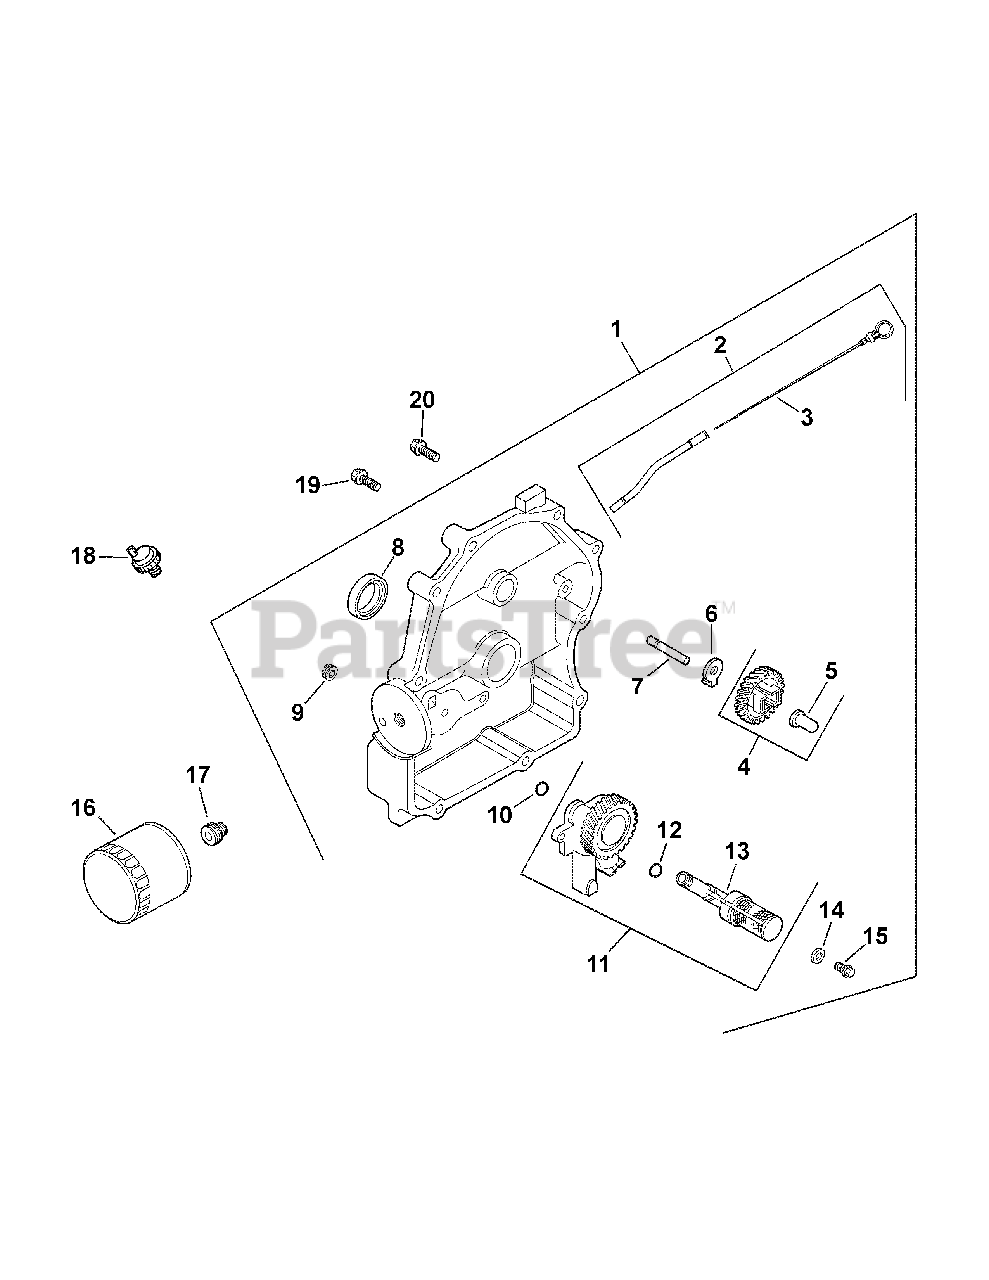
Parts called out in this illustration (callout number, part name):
1	Plate, closure ass’y
2	Kit, tube w/dipstick
4	Kit, governor gear
5	Pin, governor regulating
7	Shaft, governor gear
8	Seal, oil (PTO end)
9	Plug, pipe 1/8"
11	Oil pump ass’y
12	O-Ring, oil pick-up
13	Pick-up, oil
14	Washer, plain 6 mm
15	Screw, hex flange M6x1.0x25
17	Nipple, oil filter
18	Switch, pressure
19	Screw, hex flg, M8x1.25x45
20	Screw, hex. flange M8x1.25x45
